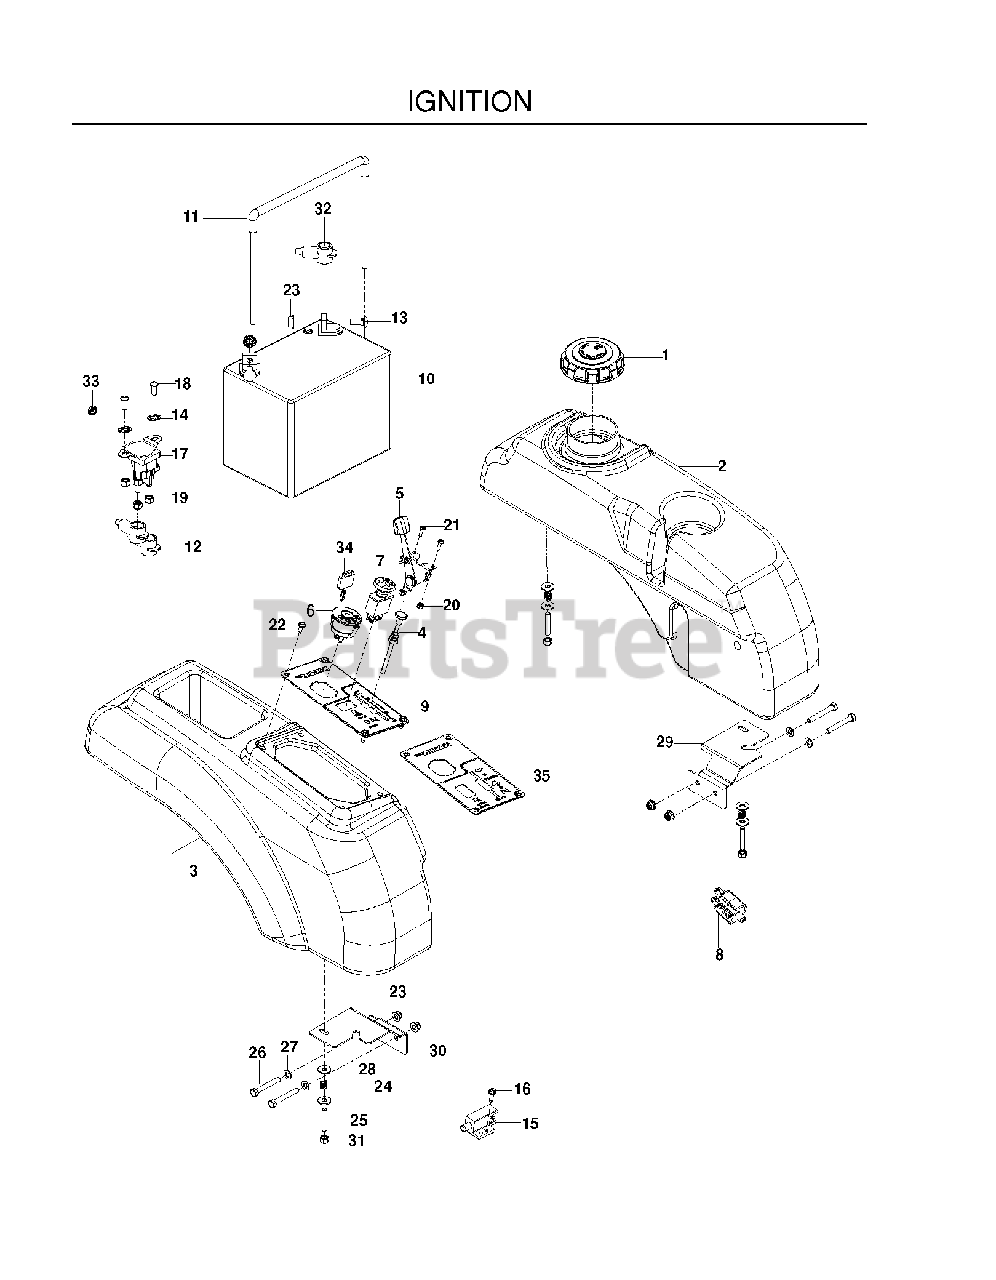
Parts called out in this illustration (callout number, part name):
1	FUEL CAP, GENERIC
2	FUEL TANK ASM LH
3	FENDER RH
4	PUSH/PULL CHOKE CABLE
5	CABLE THROTTLE
6	IGNITION SWITCH
7	SWITCH, BLADE
8	SWITCH, BRAKE 3P
9	DECAL, CONTROL PANEL SPDZTR
10	BATTERY, 12 V 330 AMP TBR
11	BATTERY TIE DOWN ASSEMBLY
12	TERMINAL COVER-SM
13	BOLT 5/16C X 3/4" CARRIAGE
14	WASHER 1/4 INT TOOTH
15	SWITCH, INTERLOCK
16	SCREW #10 X 1/2 SELF TAPPING
17	SOLENOID
18	SCR 1/4-20 X 5/8 BTN SKT HD ZD
19	NUT 1/4-20 NYLOC
20	NUT 10-24 NYLOC
21	SCREW #10-24 X 5/8
22	SCREW 1/4 X 5/8
23	5/16-18 NYLOC FLANGE NUT
25	STUD, 5/16C
26	CAPSCREW
27	FLAT WASHER 5/16 SAE
28	WASHER 5/16 FLAT
29	SUPPORT, TANK LT BLK
30	SUPPORT, TANK, RT BLK
31	NUT 5/16 NYLOC
32	INSULATOR
33	JAM NUT 1/4C
34	KEY
